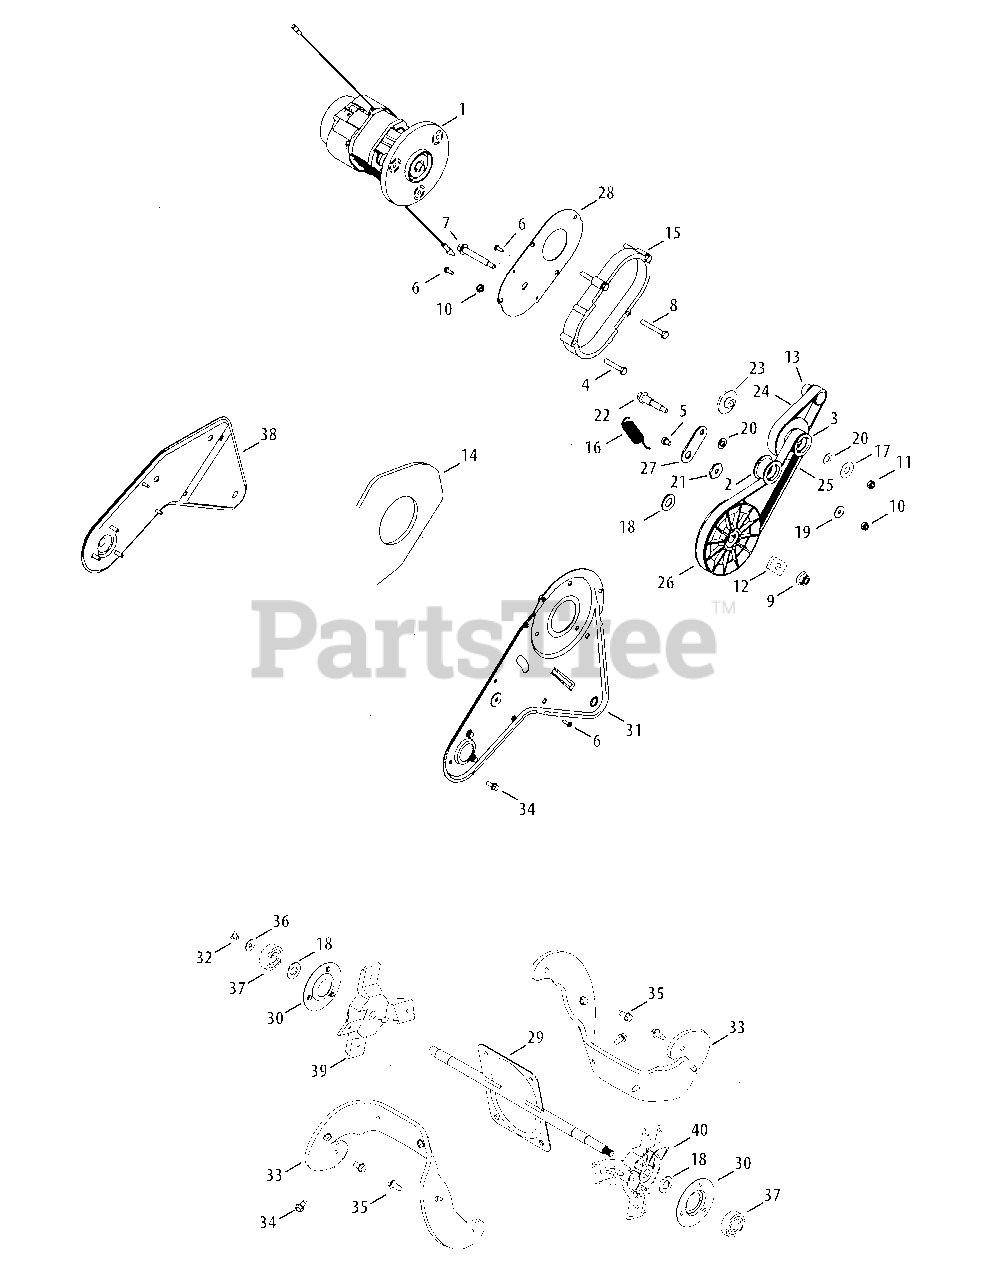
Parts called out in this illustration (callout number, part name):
1	Motor Assembly (Incl. Ref 13)
2	Pulley Assembly, Idler
3	Pulley Assembly
4	Screw, M6-1, 35.00
5	Screw, Hex Screw, M6 x 8mm
6	Screw, Tap, M4.2 x 1.4 x 13
7	Screw, Hex Flange, M8-1.25, 60mm
8	Screw, M6-1, 45.00
9	Nut, Flange Lock, 3/8-16, Nylon
10	Nut, Hex Lock, M6-1
11	Nut, Hex Lock, M8-1.25, Nylon
12	Plate, Drive Pulley
13	Pulley, 5mm, 15 Tooth
14	Gasket, Foam
15	Spacer, Motor Mount
16	Extension Spring, Idler
17	Washer, Flat, .406 x 1.0 x .030
18	Washer, Flat, M12
19	Washer, Flat, 6.4 Id x 18 OD
20	Washer, Flat, 8.4 x 16 x 1.60
21	Spacer, Shoulder, Hex, M6
22	Screw, Shoulder
23	Spacer, 8.35 x 16 x 11.65
24	Belt, Sync
25	Belt, Poly, 6 Rib
26	Pulley, Auger, 6 Rib
27	Bracket, Idler
28	Plate, Motor Mount
29	Auger Weldment
30	Cover, Bearing
31	Outer Frame, LH
32	Screw, Hex Screw, M6 x 8mm
33	Paddle Auger, Rubber
34	Screw, Self-tapping, 1/4-20, 0.500
35	Screw, 1/4-10 x .625
36	Washer, Flat, 6.4 Idx18 OD
37	Bearing, Ball, 12 x 37 x 12
39	Bracket, Paddle, Mount, LH
40	Bracket, Paddle, Mount, RH
